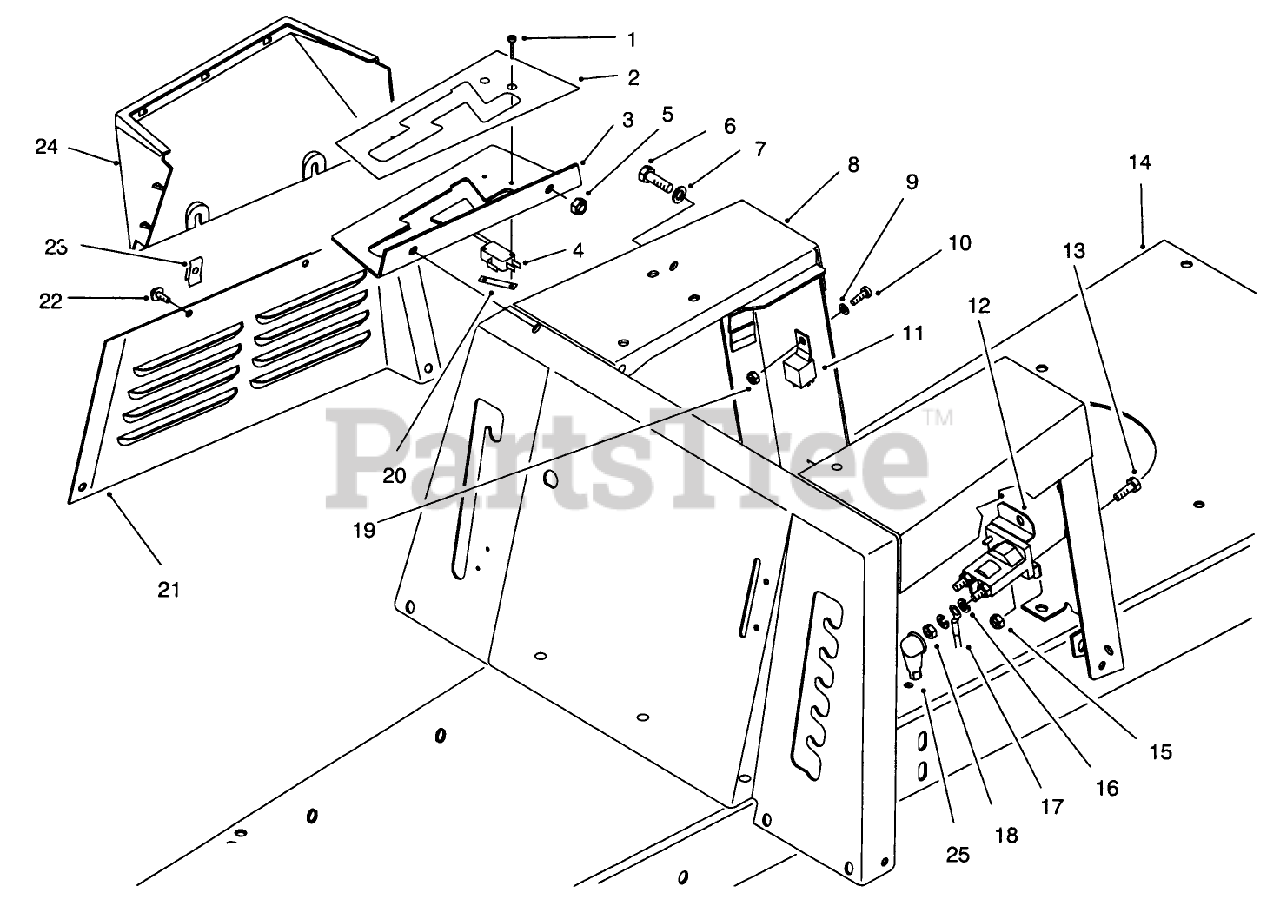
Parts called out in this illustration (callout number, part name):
2	DECAL - SHIFT PATTERN
4	SWITCH-MICRO
5	NUT-LOCK, NI
6	SCREW-HH
7	WASHER-PLAIN
9	WASHER-FLAT
11	RELAY
13	SCREW-HH
15	NUT-LOCK, NI
16	WASHER-LOCK
17	WIRE ASM
18	NUT-JAM
19	NUT-LOCK, NI
20	NUT-SPEED
22	SCREW-HWH
23	NUT-CLIP,U
24	COVER-SHIFT GATE
25	BOOT-INSULATOR, TERMINAL
